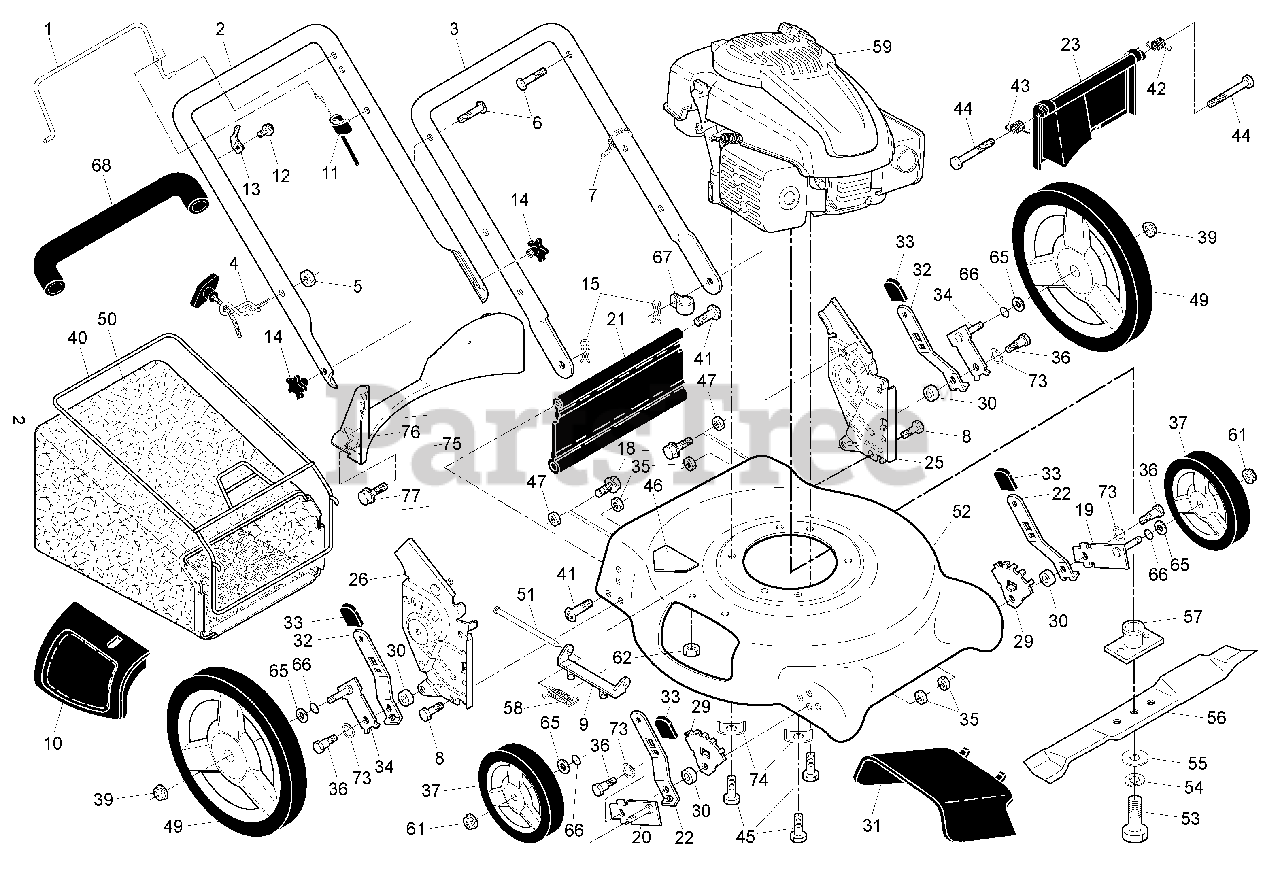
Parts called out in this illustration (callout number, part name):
1	Control Bar
2	Upper Handle
3	Lower Handle
4	Rope Guide
5	Locknut, Hex 1/4-20
6	Handle Bolt
7	Wire Tie
8	Hex Bolt 5/16-18 x 3/4
9	Hinge Bracket Assembly
10	Mulcher Door
11	Engine Zone Control Cable
12	Hex Washer Head Screw #10-24 x 1/2
13	Up-Stop Bracket
14	Handle Knob
15	Hairpin Cotter
18	Screw 1/4-20 x 3/8
19	Axle Arm Assembly, Front, LH
20	Axle Arm Assembly, Front, RH
21	Kit, Rear Skirt
22	Selector Spring, Front
23	Rear Door Assembly
25	Handle Bracket Assembly, LH
26	Handle Bracket Assembly, RH
29	Wheel Adjusting Bracket, Front
31	Discharge Defl ector
32	Selector Spring, Rear
33	Selector Knob
34	Axle Arm Assembly, Rear, LH
35	Nut, Hex
36	Shoulder Bolt 5/16-18
37	Wheel & Tire Assembly, Front 8 x 1-3/4
39	Nut, Hex, Flangelock
40	Frame, Grassbag
41	Hinge Screw
42	Spring, Rear Door, LH
43	Spring, Rear Door, RH
44	Bolt, Rear Door
45	Hex Head Thread Rolling Screw 3/8-16 x 1
46	Danger Decal
47	Locknut, Hex 5/16-18
48	Axle Arm Assembly, Rear, RH
49	Wheel & Tire Assembly, Rear 12 x 1-3/4
50	Grassbag
52	Kit, Lawn Mower Housing Assembly
53	Hex Head Screw 3/8-24 x 1-3/8 Grade 8
54	Helical Lockwasher
55	Hardened Washer
56	21" Blade
57	Blade Adapter
58	Spring, Torsion
61	Nut, Hex, Flangelock
62	Nut, Hex, Nylock 1/4-20
65	Washer, Flat
67	Clip, Cable
68	Grip, Foam
73	Washer, Flat
74	Washer, Special, Engine, Zinc-Plated
75	Kit, Rear Baffle
76	Baffl e, Rear
77	Screw, Rear Baffle
